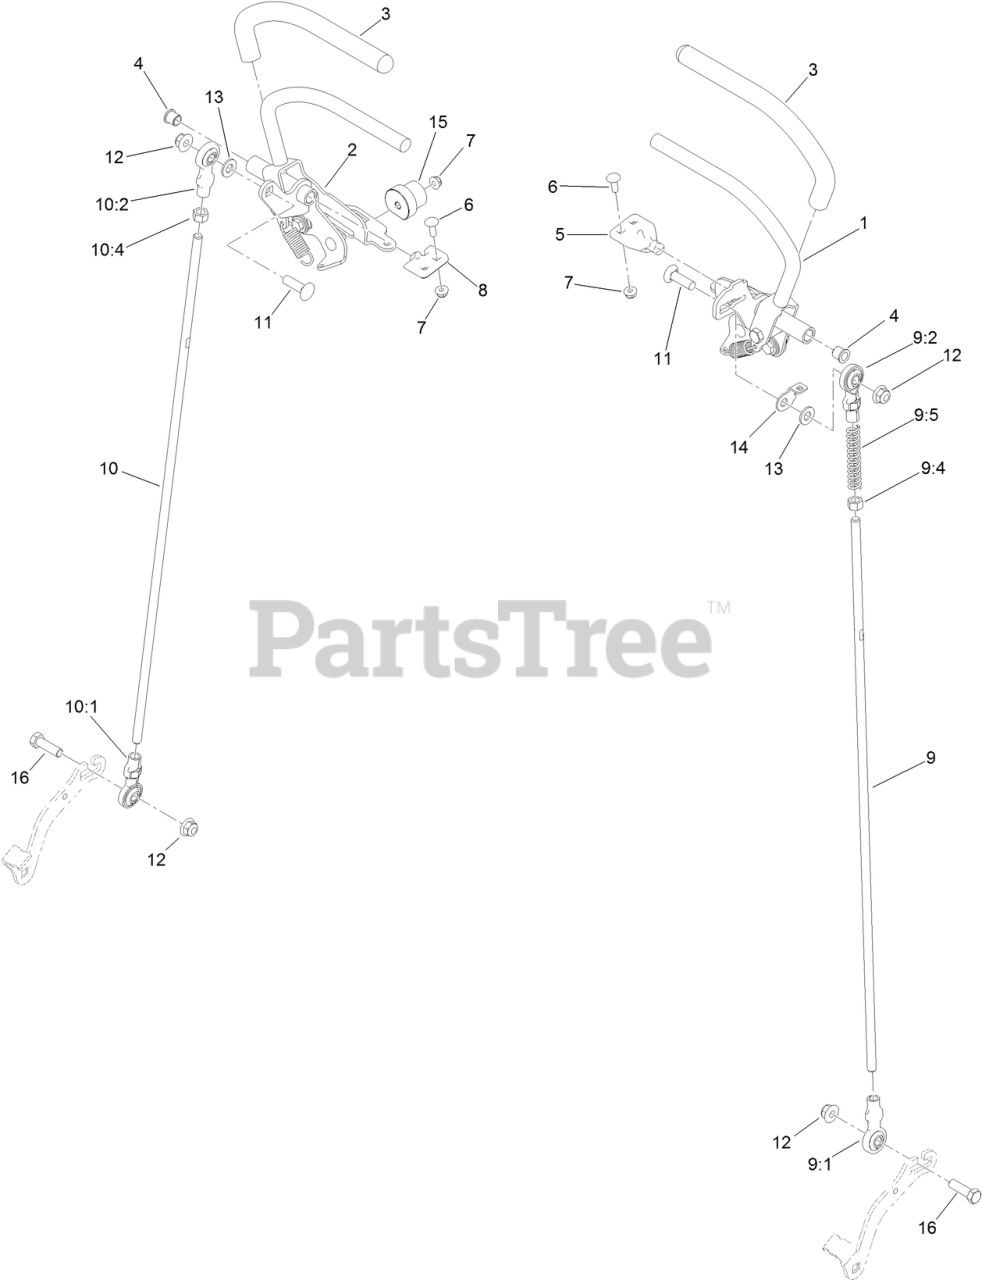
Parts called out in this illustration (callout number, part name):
1	LH CONTROL HANDLE ASM
2	RH CONTROL HANDLE ASM
4	BEARING
5	TAB-PIVOT, LH
6	BOLT-CARR
7	NUT-HF
8	TAB-PIVOT, RH
9	LH CONTROL ROD ASM
9:1	BALL JOINT-LH
9:2	BALL JOINT-RH
9:4	NUT-HEX
9:5	SPRING-RETURN, NEUTRAL
10	RH CONTROL ROD ASM
10:1	BALL JOINT-LH
10:2	BALL JOINT-RH
10:4	NUT-HEX
11	SCREW-CARR
12	NUT-HF, NI
13	WASHER-FLAT
14	BRACKET-ADJUSTMENT, SPEED
16	SCREW-HH
